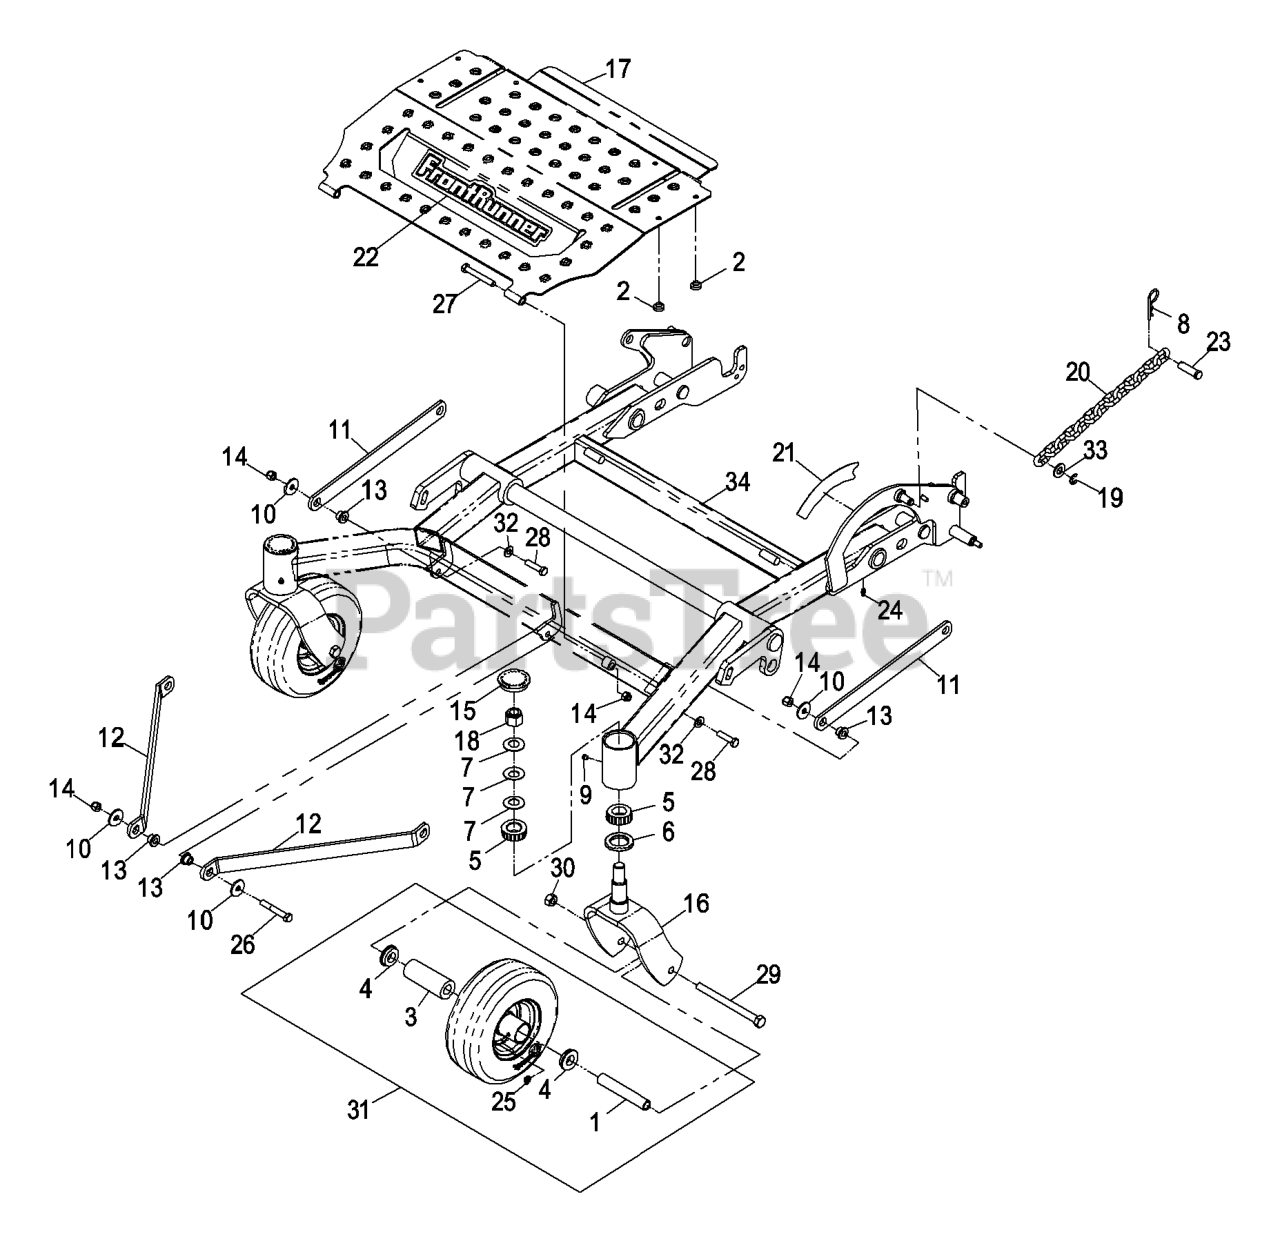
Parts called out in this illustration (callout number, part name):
3	BEARING
4	BUSHING
5	Cone-Bearing Tapered Roller
6	SEAL-GREASE
7	WASHER-BELLVILLE
8	PIN-COTTER
11	FLAT,STRUT
12	FLAT,STRUT ANGLED
13	SPACER-STRUT
14	NUT-LOCK, NI
15	CAP-GREASE
16	WLD,CASTER FORK FMZ
17	ASM,FRONT COVER W/DECAL
18	NUT-LOCK, NI
19	RING-RETAINING, EXTERNAL
21	DECAL,DECK HEIGHT
22	DECAL,FRONTRUNNER
23	PIN-CLEVIS
24	FITTING-GREASE
25	FITTING-GREASE
26	BOLT-CARR
27	SCREW-HH
28	SCREW-HH
29	SCREW-HH
30	NUT-HEX
31	KIT, SP CASTER WHEEL REPL
32	WASHER-FLAT
33	WASHER-FLAT
34	ASM,FRONT FRAME W/DECAL 5
